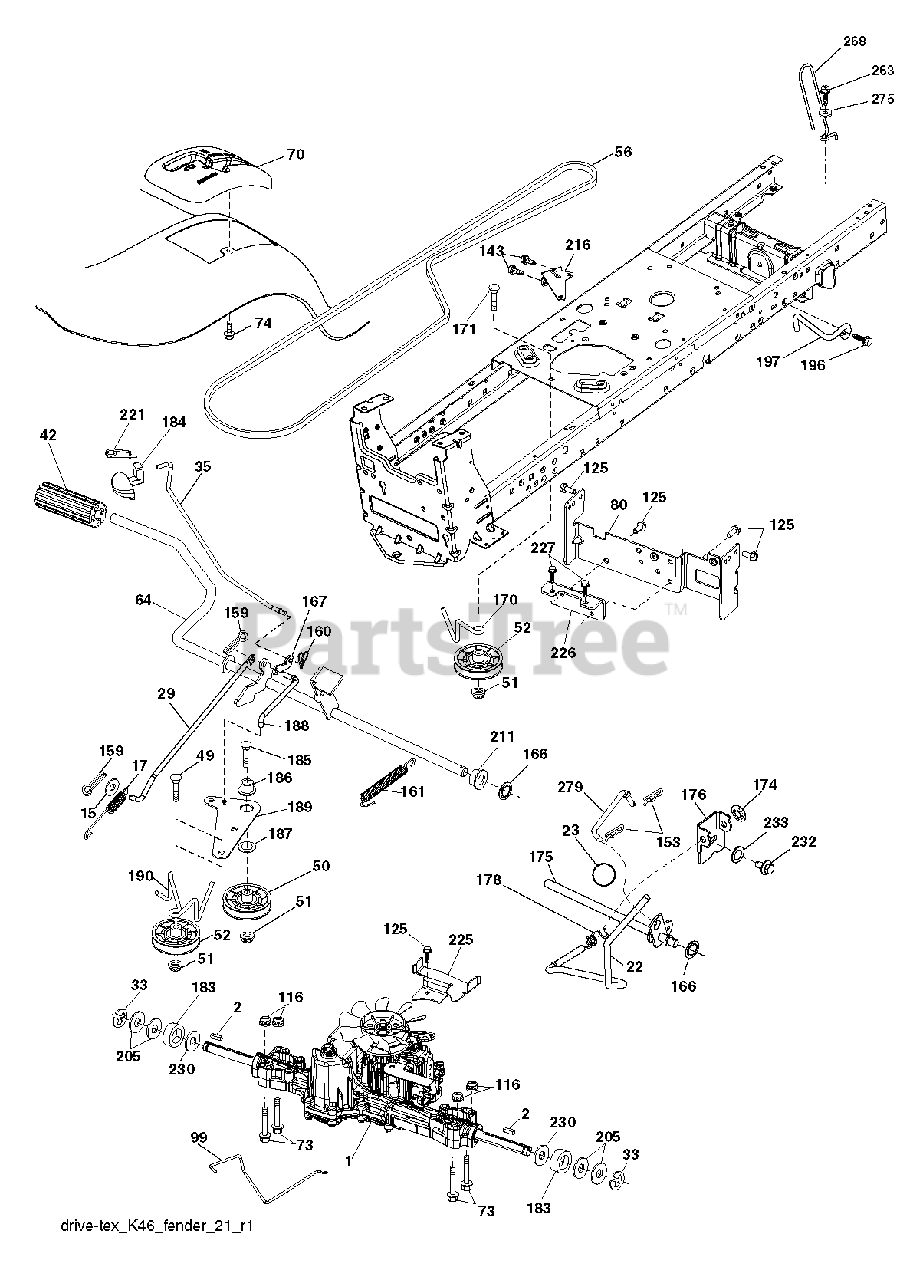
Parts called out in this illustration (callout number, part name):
2	SQUARE KEY
17	SPRING.BRAKE.K46.GREEN
22	ROD.SHIFT.FENDER.TLT.2006
23	PISTOL KNOB
29	ROD.BRAKE.K46
33	E-RING LT
35	ROD.BRAKE.PARTK.HUSQ.TEX
42	PEDAL COVER T
49	BOLT
50	IDLER.FLAT.910.OFFSET
51	NUT LOCK FLG 3/8-16 UNC
52	IDLER.V-GROOVE.910.OFFSET
64	SHAFT.ASM.PEDAL.BRAKE.
70	CONSOLE.SHIFT.STL.HYD.BLACK
73	BOLT
74	SCREW.HI-LO.CONSOLE
80	STRAP.TORQUE.K46.K57R.TT
99	ROD.SPRING.BYPASS.K46.LT.Z
116	NUT LOCK HEX FLANGE 5/16-18
125	SCREW
143	SCREW LT
153	RETAINER M
159	COTTER PIN
160	RETAINER CLIP
161	SPRING, RETURN LT
166	NUT.PUSH.625
167	LATCH.BRAKE.SPRING
170	KEEPER.V-IDLER.CENTER.
171	BOLT
174	NUT.PUSH.500.2006
175	SHAFT ASM SHIFT
176	ARM.CLEVIS.ROD.SHIFT
178	SPRING.SHIFT.GT2006
183	SPACER AXLE
184	HANDLE.PARKG.BRK.HUSQ/PRED.667
186	SPACER.RETAINER
187	WASHER 12/32X2X10GA
188	LINK.CLUTCH.GROUND.DRIVE
189	BELLCRANK.GROUND.DRIVE.TEX.
190	KEEPER.BELLCRANK.DRIVE
196	SCREW 3/8-16X1
197	LINK.CLUTCH.ANIT-ROTAT
211	BUSHING.SHAFT.BRAKE.HAND
216	BRACKET.PULLEY.IDLER.W/TEX
221	RETAINER.SPRING.CLIP.H
225	KEEPER.BELT.TRANSAXLE.K46
226	BRACKET.MOUNT.TORQUE.K46.TLT
227	SCREW
230	WASHER.HARDENED
232	BOLT FIN HEX 7/16-14 X 1
233	WASHER SERRATED
263	SCREW, 3/8-16X3/4
275	WASHER
279	LINK SHIFT
